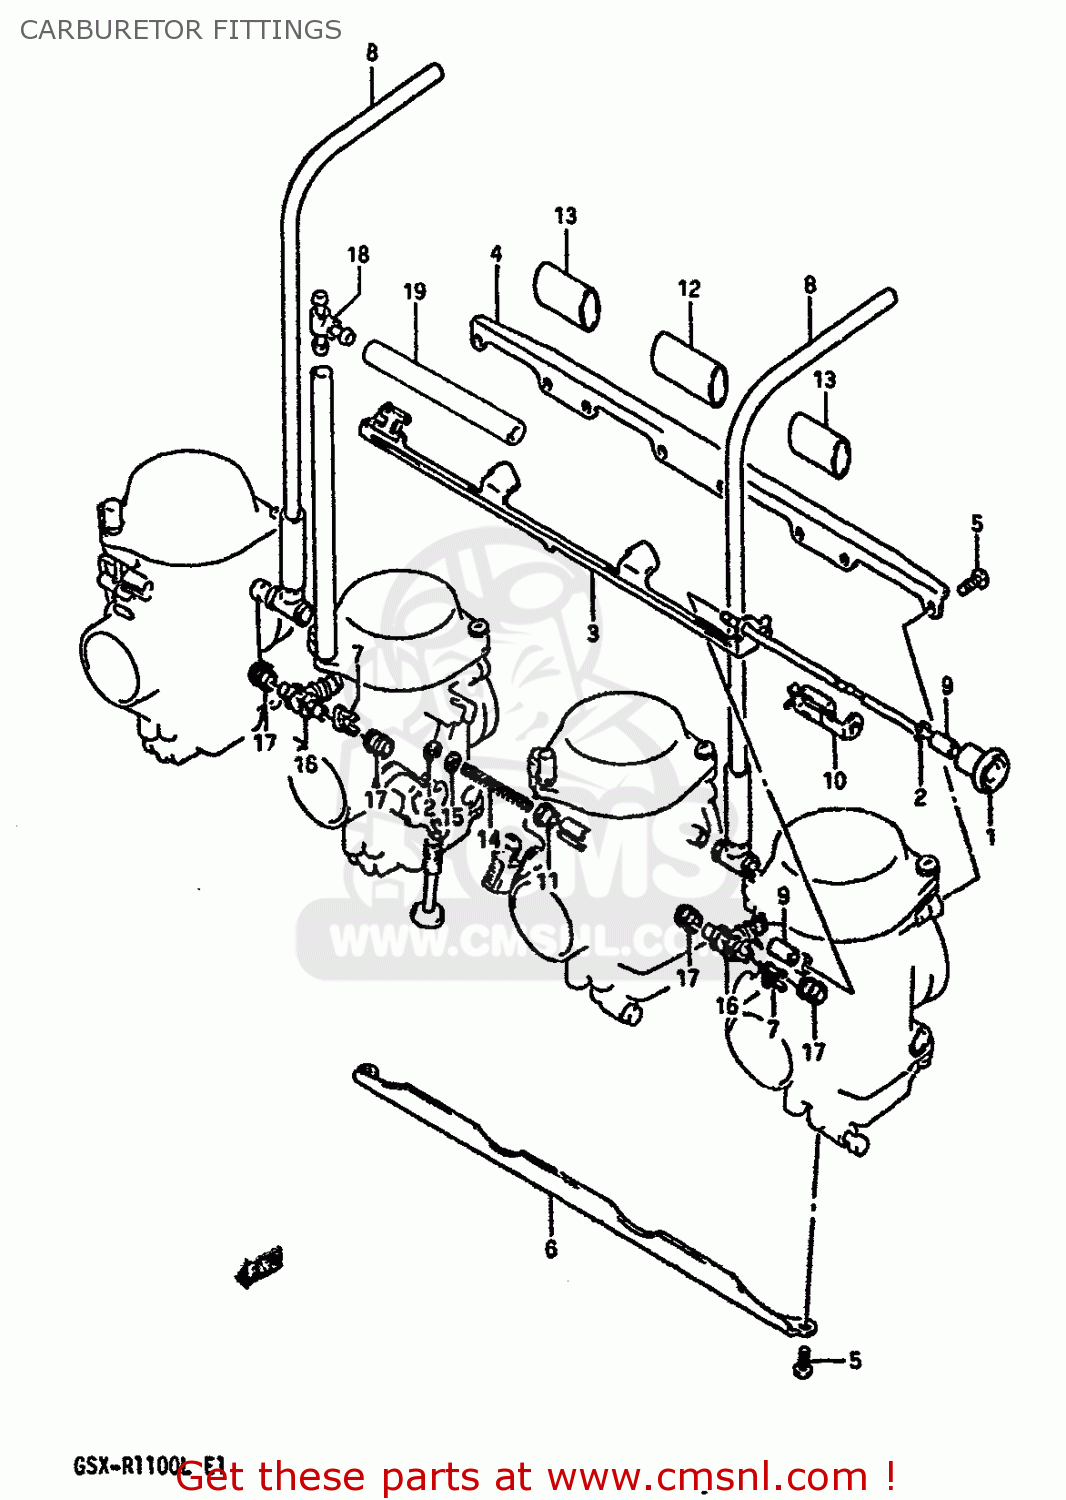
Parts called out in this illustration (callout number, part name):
1	SHAFT ASSY,STARTER
2	E RING
3	CARBURETOR ASSY,MR
4	CARBURETOR ASSY,RH
5	SCREW
6	VALVE,PISTON
7	CLIP
8	HOSE
9	RING
10	PLATE
11	NEEDLE,JET
12	NUT
13	HOSE
14	SPRING
15	WASHER
16	NIPPLE
17	SEAL
18	NIPPLE
19	HOSE
20	SHAFT ASSEMBLY
21	SEAL
22	GASKET,THROTTLE SHAFT (NAS)
23	SCREW
24	SCREW
25	VALVE,THROTTLE(125)
26	GASKET,FLOAT CHAMBER (NAS)
27	JET(40)
28	JET,NEEDLE(O-9)
29	O RING
30	JET,MAIN(110)
31	PLUG
32	FLOAT/NEEDLE VALVE ASSY
33	O RING
34	O-RING,NEEDLE VALVE
35	SCREW
36	SCREW
37	SPRING
38	SPRING
39	CAP
40	CLIP
41	SHAFT ASSEMBLY
42	RING
43	COVER,DIAPHRAGM
44	CAP,STARTER
45	HOSE
46	SCREW
47	SPRING
48	WASHER
49	HOLDER,GUIDE
50	SPRING
51	PLUNGER ASSY
52	SCREW,PILOT
53	SPRING
54	WASHER
55	O RING,PILOT AIR SCREW
56	JET,AIR(1.35)
